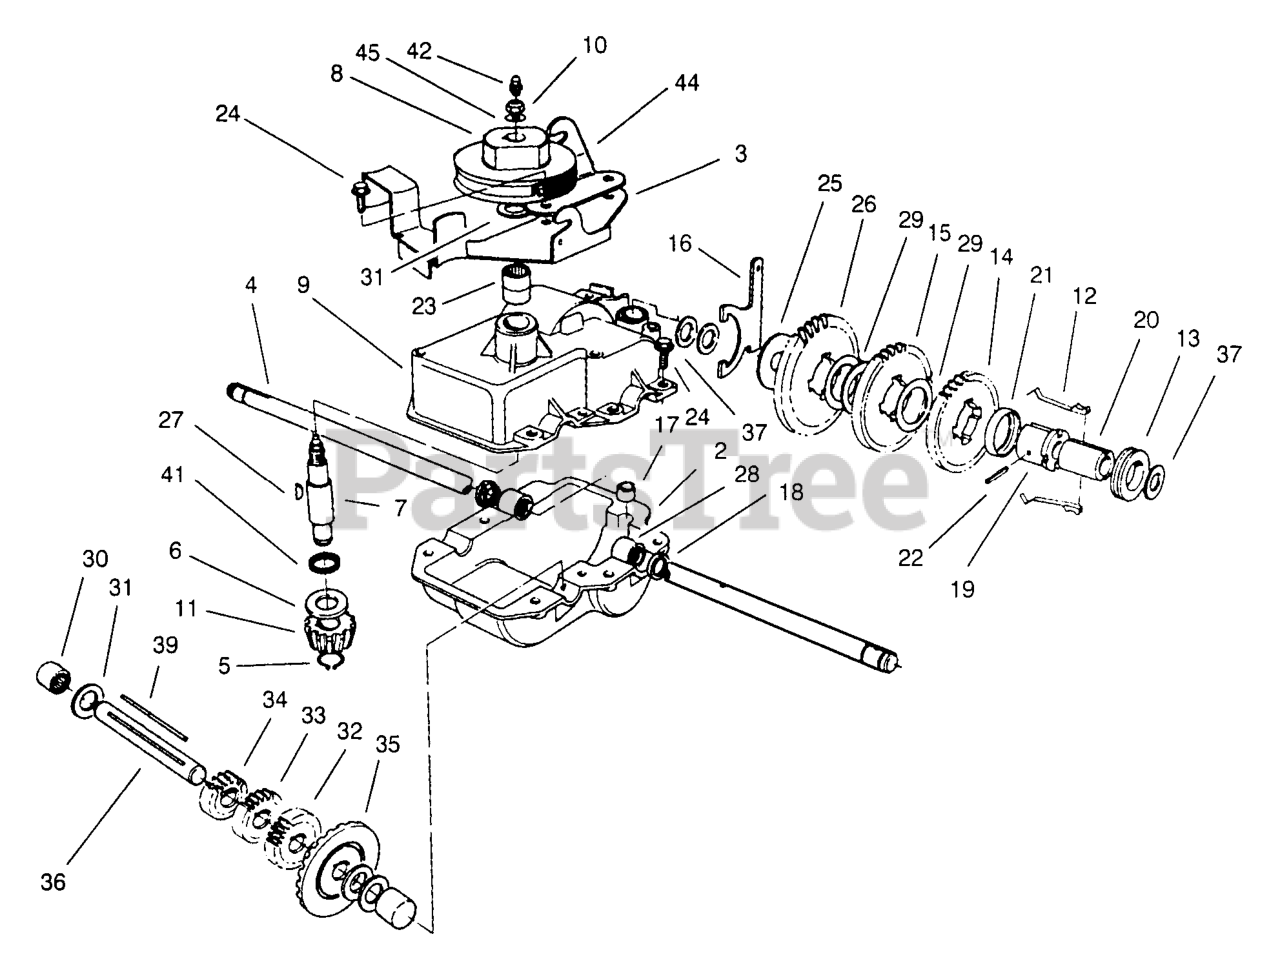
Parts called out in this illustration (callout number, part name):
3	BRACKET-GUIDE, BELT
4	SHAFT-OUTPUT
5	RING-RETAINING
6	WASHER-THRUST
10	NUT-HEX
11	PINION-BEVEL
12	KEY-SHIFT
13	COLLAR-SHIFT
14	GEAR-38T
15	GEAR-42T
16	YOKE-SHIFT
17	BUSHING-YOKE
18	SEAL-OIL
19	SLEEVE-GEAR
21	RETAINER-KEY
22	PIN-GROOVE
23	BEARING-NEEDLE
24	SCREW-HWHTF
27	KEY-WOODRUFF
30	BEARING-NEEDLE, CLOSED
31	WASHER-THRUST
32	GEAR-18T
33	GEAR-14T
34	GEAR-12T
35	GEAR-BEVEL
36	SHAFT-INTERMEDIATE
37	WASHER-PLAIN
42	FITTING-GREASE, ZERK
44	BRACKET-ENGAGE, TRACTION
45	WASHER-FLAT
